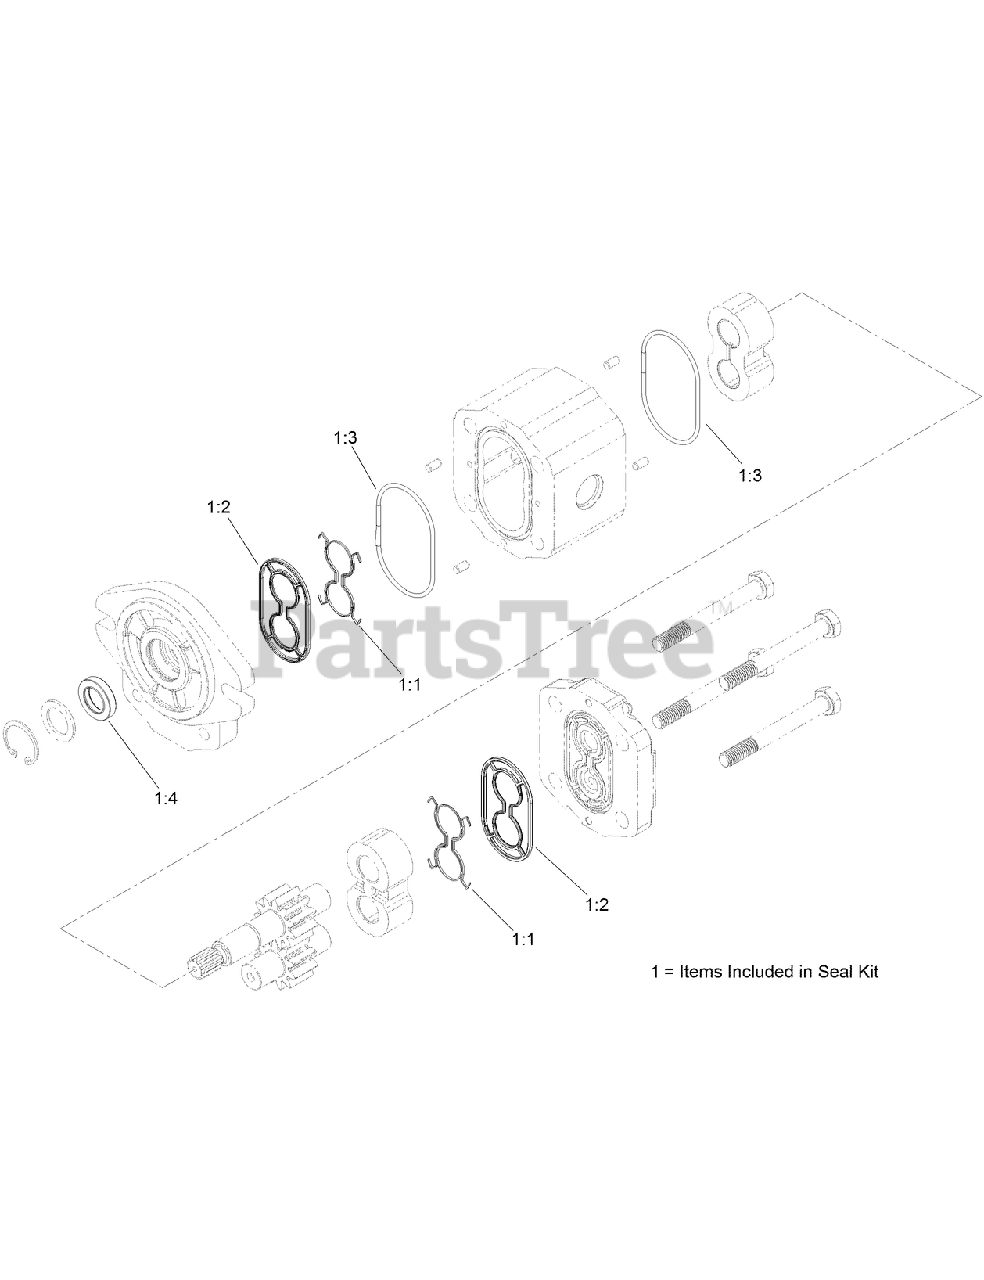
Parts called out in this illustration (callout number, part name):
1:1	SEAL
1:2	PRESSURE SEAL
1:3	O-RING
1:4	Seal-Lip, Shaft
